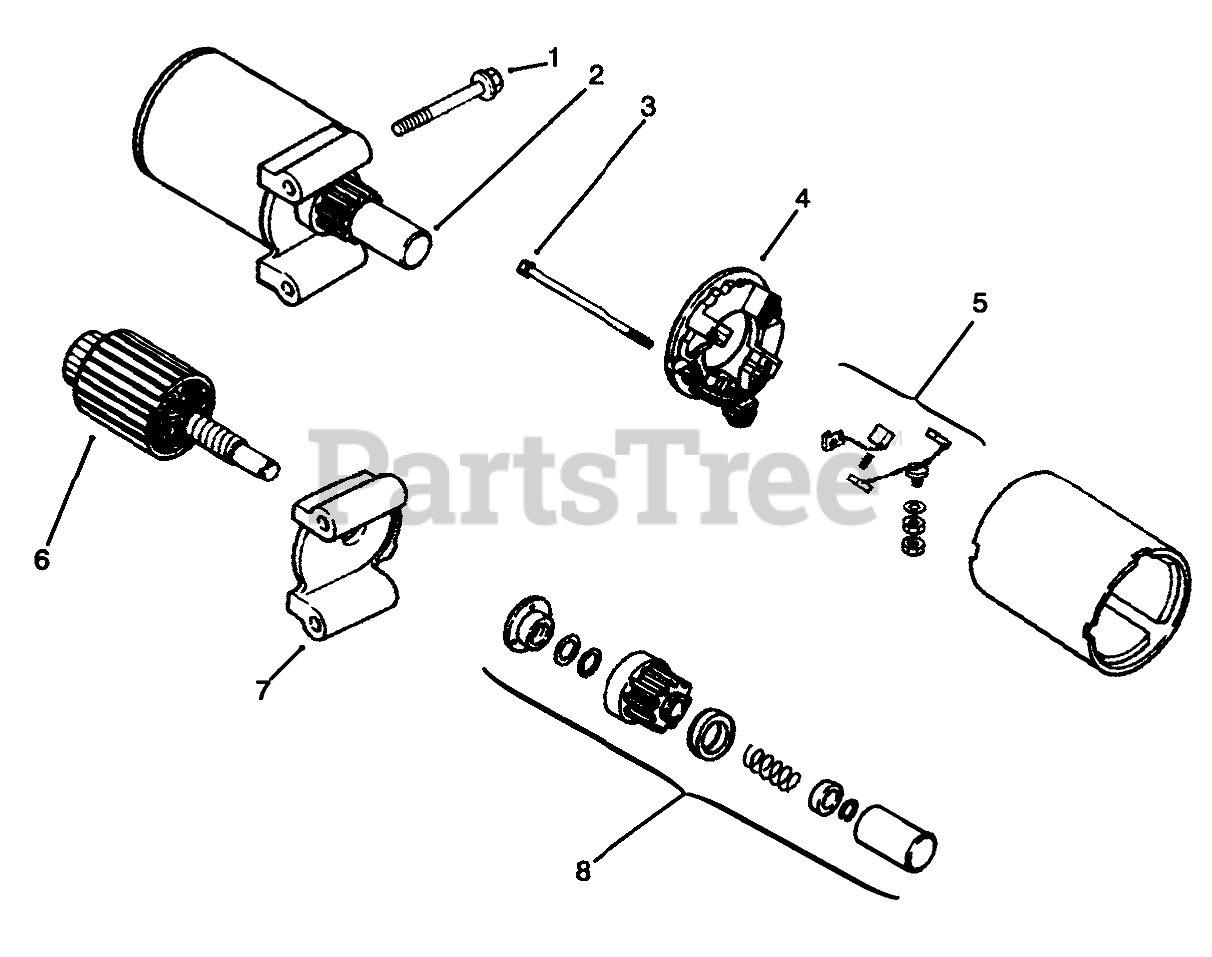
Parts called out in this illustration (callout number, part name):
1	Screw M8x1.25x70
2	Starter ASM Incl 3-8
3	Screw
4	Cap-Communtator Incl 5
5	Kit-Brush & Spring
6	Armature
7	Cap-Drive End
8	Kit-Drive
